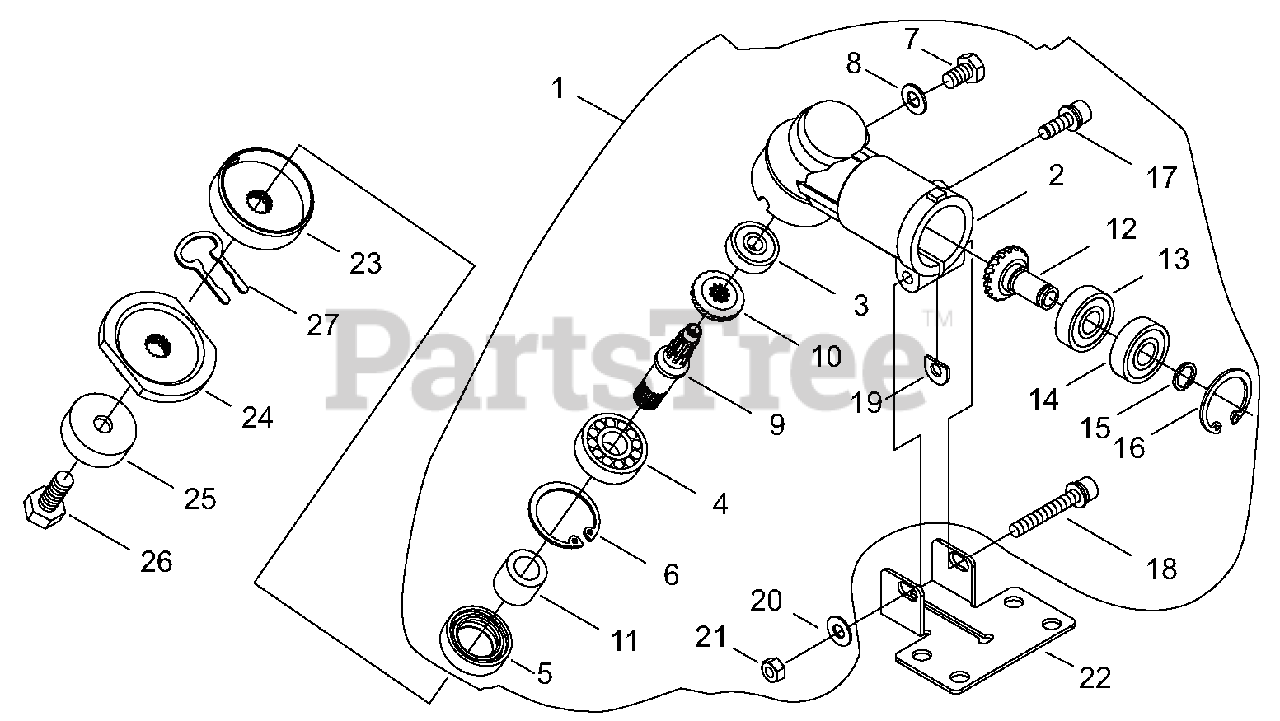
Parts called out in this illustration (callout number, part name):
1	GEAR CASE ASSY
2	HOUSING, GEAR CASE
3	BEARING, BALL 626 DDU
4	BEARING, BALL 6000
5	SEAL, OIL
6	RING, SNAP Ø26
7	BOLT M6×10
8	WASHER
9	SHAFT, GEAR
10	GEAR, BEVEL
11	SPACER
12	GEAR, PINION
13	BEARING, BALL 608
14	BEARING, BALL 608ZZ
15	RING, SNAP
16	RING, SNAP Ø22
17	BOLT M5×16
18	BOLT M5×35
19	D-WASHER
20	WASHER 5.5×12×0.8
21	NUT M5
22	PLATE, SHIELD MOUNTING
23	PLATE, ADAPTOR - UPPER
24	PLATE, ADAPTOR - LOWER
25	GUARD, BOLT
26	BOLT M7×18
27	CLIP, BLADE
